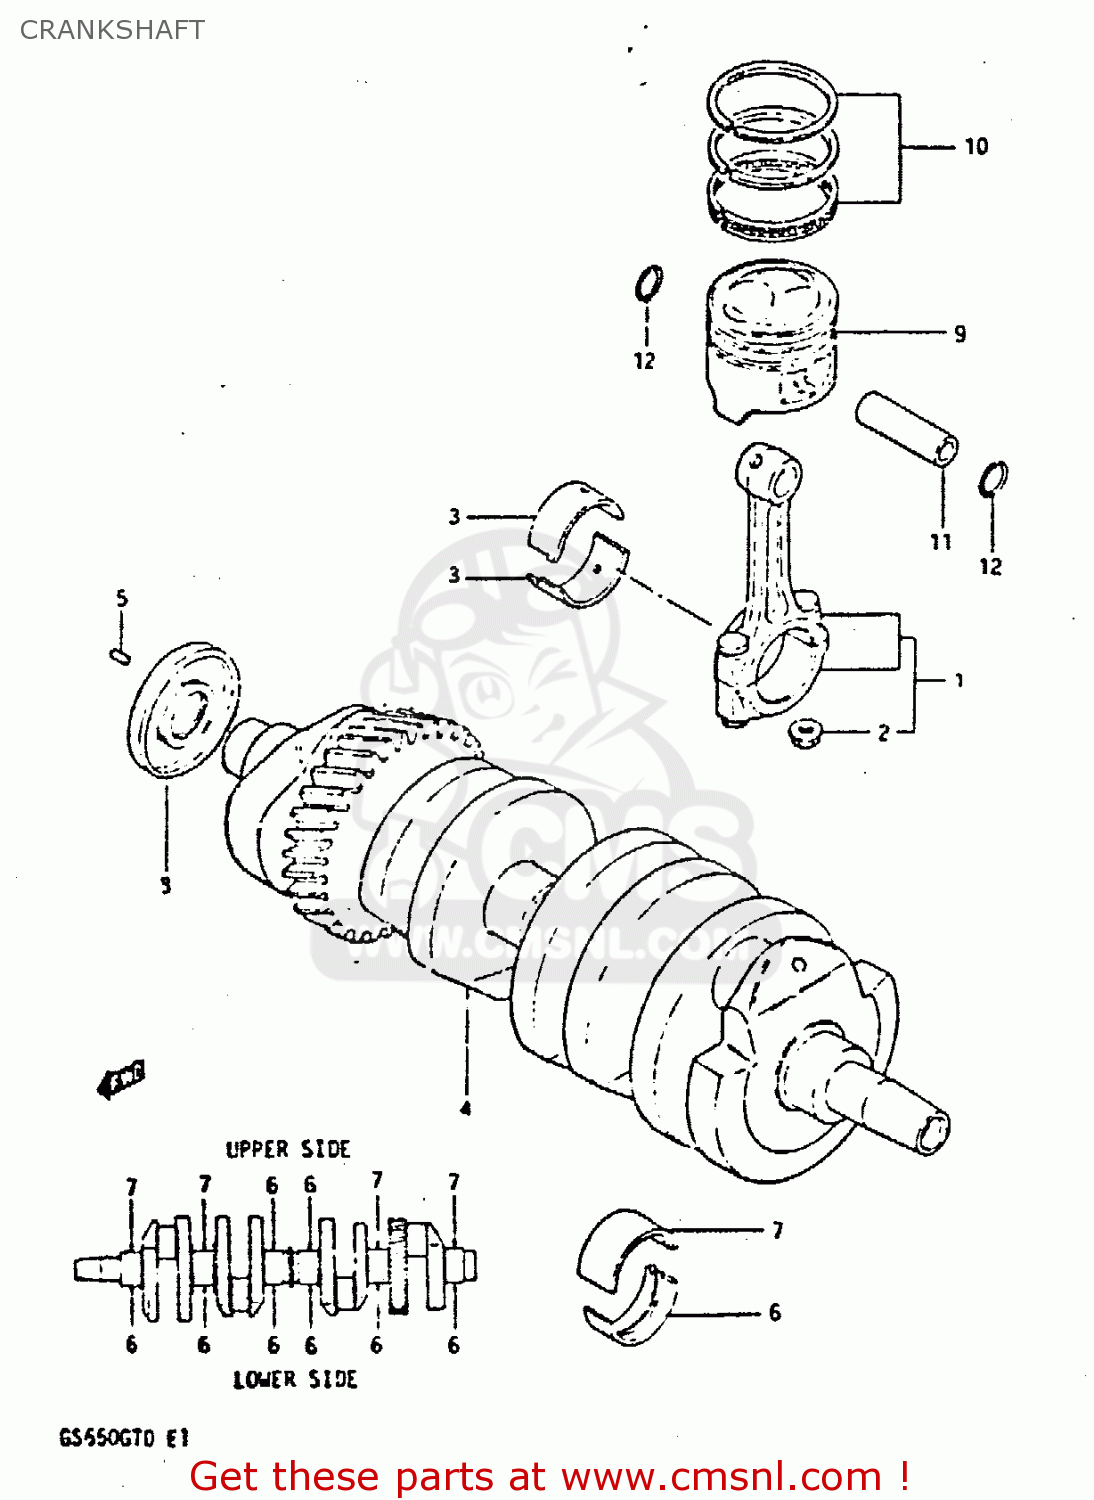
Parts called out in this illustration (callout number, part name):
1	ROD ASSEMBLY,CONNECTING
2	NUT
3	BEARING,CRANK PIN
4	CRANKSHAFT ASSEMBLY
5	PIN
6	METAL CRANKSHAFT
7	METAL CRANKSHAFT
8	SEAL,OIL(30X60X8)
9	PISTON
10	RING SET,PISTON
11	PIN,PISTON
12	CIRCLIP
